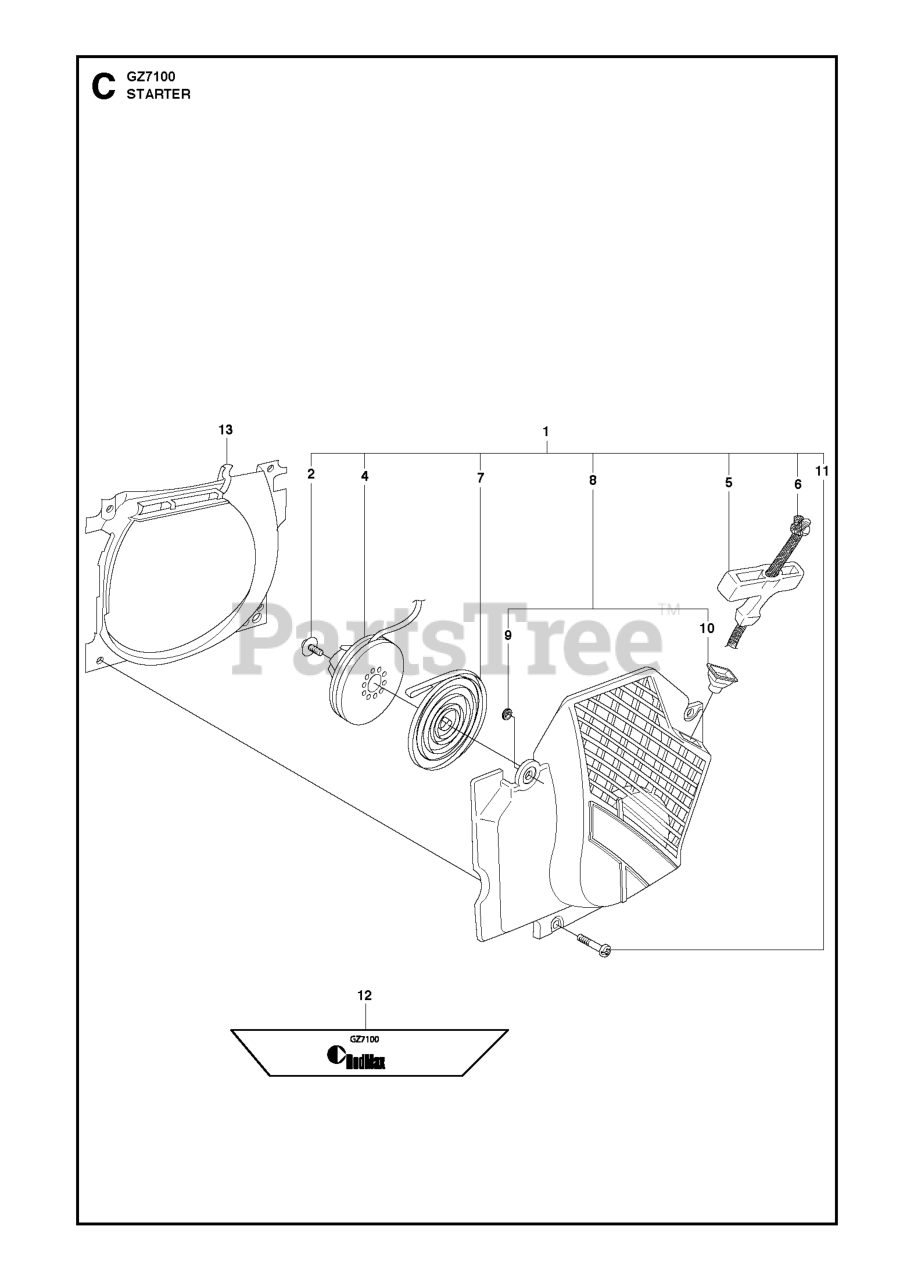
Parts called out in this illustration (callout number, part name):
1	STARTER ASSY
2	SCREW ITXSCFT WASHER PW5.5X16/
4	STARTER PULLEY
5	STARTER HANDLE
6	STARTER CORD
7	SPRING
8	STARTER HOUSING
9	BUSHING
10	SLEEVE
11	SCREW CITXPANMO
12	LABEL GZ7100
13	AIR CONDUCTOR
